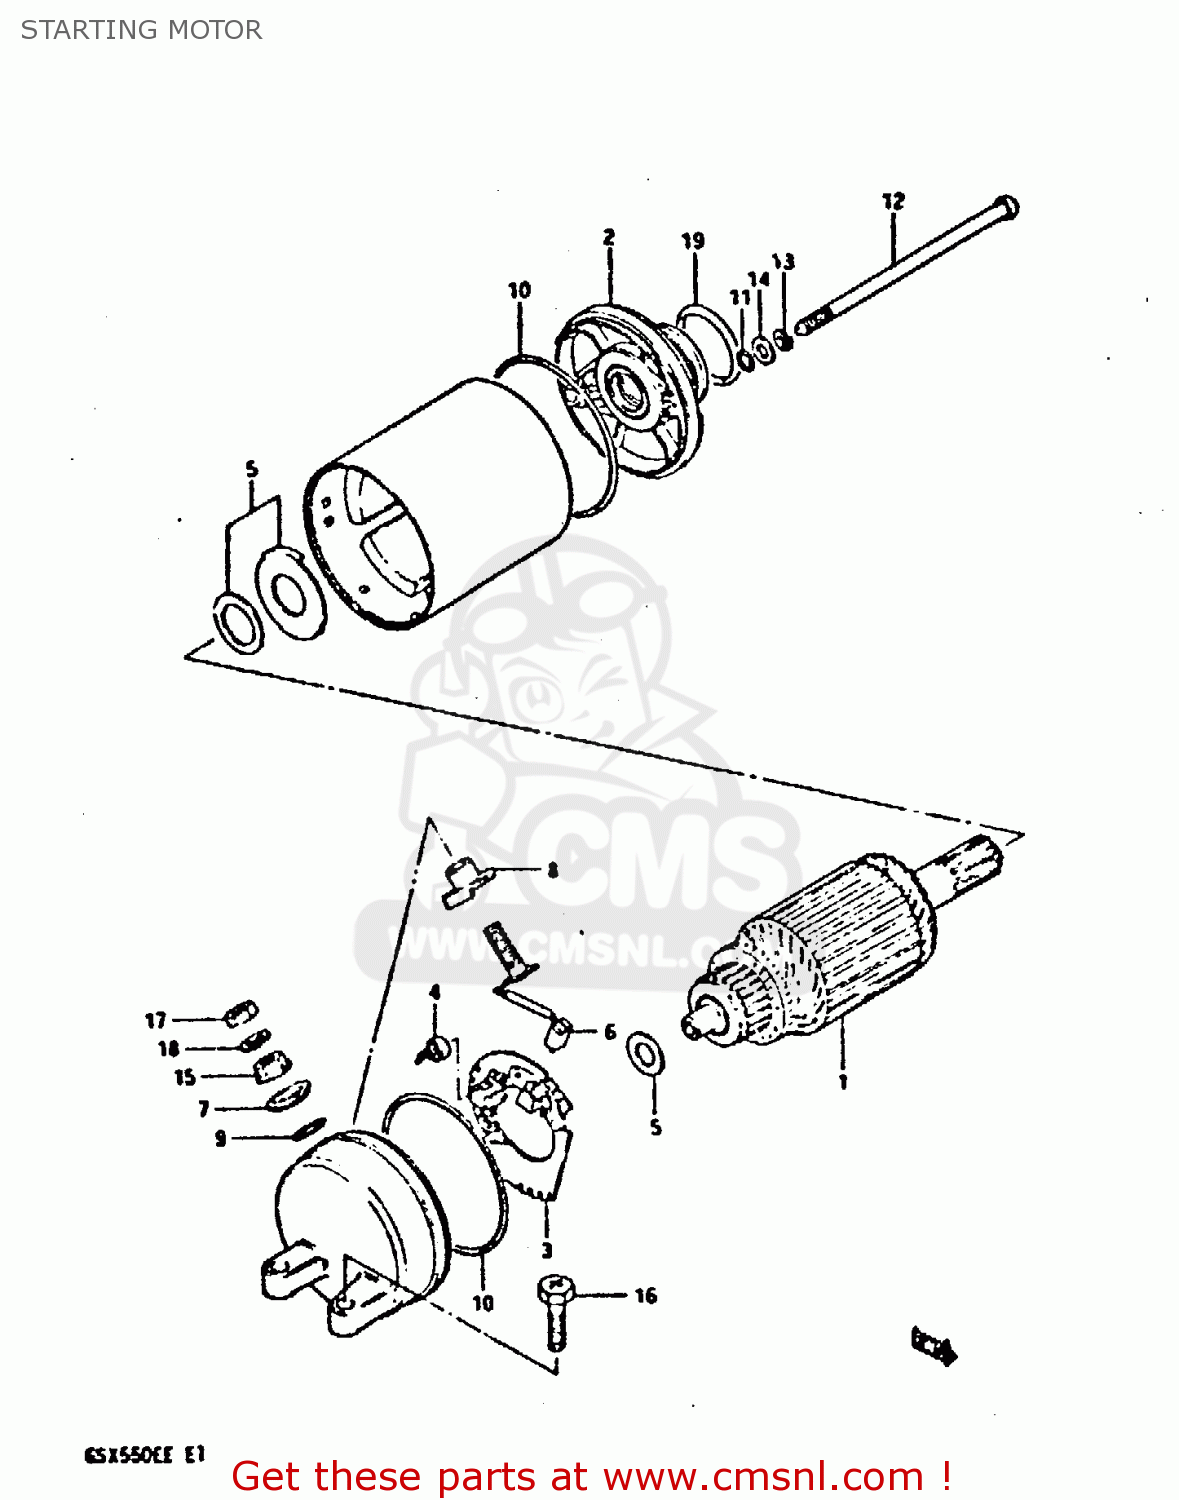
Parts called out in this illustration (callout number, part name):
1	ARMATURE
2	BRACKET SET,STARTING MOTOR
3	HOLDER,BRUSH
4	SPRING
5	SHIM SET,STARTING MOTOR
6	BRUSH SUB ASSY,STARTING MOTOR
7	BUSHING
8	BUSH,B
9	O RING
10	O RING
11	O RING
12	BOLT
13	LOCK WASHER
14	WASHER
15	NUT
16	BOLT
17	NUT
18	WASHER,LOCK
19	O RING(D:3,ID:24.5)
